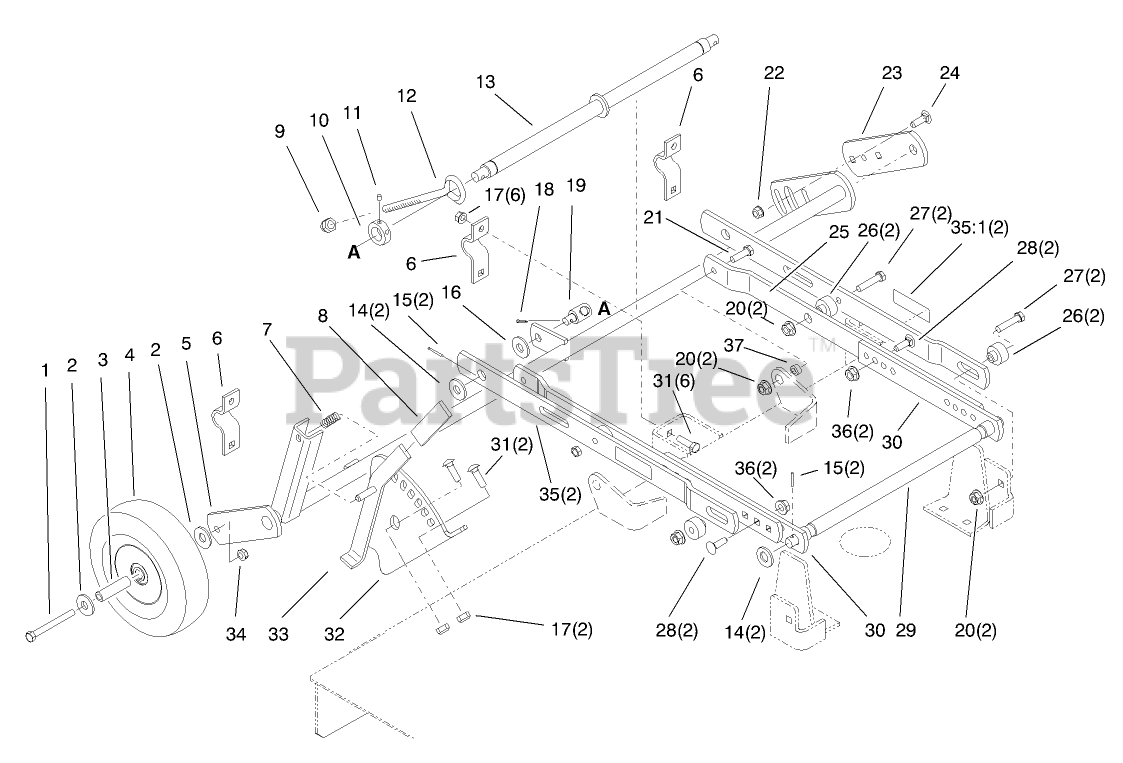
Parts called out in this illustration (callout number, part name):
1	SCREW-HH
2	WASHER-FLAT
3	SPACER
5	SUPPORT-WHEEL, 60"
7	SPRING-COMPRESSION
9	NUT-LOCK, NI
10	COLLAR
11	SCREW-SET, HSH
12	ROD-ADJUSTMENT, LEVEL
13	SHAFT ASM-LEVELER
14	WASHER-FLAT
15	PIN-ROLL, SPIROL
16	WASHER-FLAT
17	NUT-LOCK, NI
18	PIN-COTTER
19	TRUNNION
21	SCREW-HH
22	NUT-FLANGE
23	SUPPORT-GAGE WHEEL
24	BOLT-CARR
25	DRAFTBAR
26	SPACER
27	SCREW-HH
28	SCREW-CARR
31	BOLT-CARR
32	QUADRANT-DECK
33	LEVER-HOC
35	LH LEVELER ASM *B
35	RH LEVELER ASM *B
35:1	DECAL-WARNING
36	NUT-LOCK, CONE
37	SPACER
